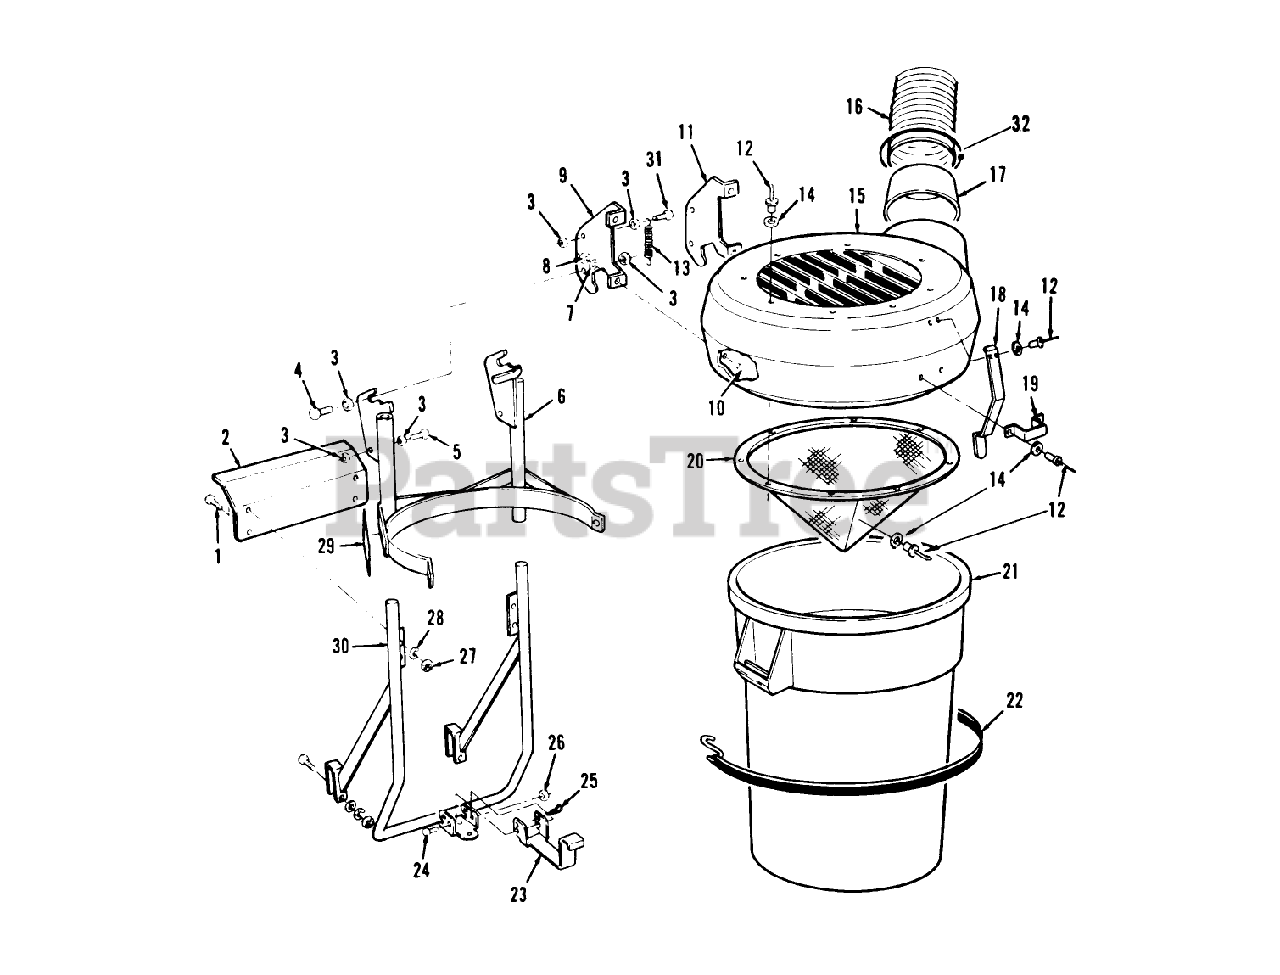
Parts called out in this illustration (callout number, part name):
1	SCREW-HH
2	SHIELD-HEAT B
3	NUT-HEX
4	SCREW-HH
5	SCREW-HH
6	Support-Canister
7	WASHER-PLAIN
8	NUT-LOCK, NI
9	LH TOP BRACKET B
10	SCREW-HH
11	RH TOP BRACKET B
12	RIVET-POP
13	SPRING-EXTENSION
14	Washer
15	TOP-CANISTER
16	HOSE 6" X 48"
17	SEAL ASSEMBLY NP
18	LATCH-BAGGER TOP B
19	BRACKET B
20	SCREEN-BAGGER TOP
21	CANISTER
22	STRAP B
23	BRACKET-SUPT B
24	Screw-Cap Hex. Hd.
25	Hairpin
26	NUT-LOCK, NI
27	NUT-LOCK, NI
28	WASHER-PLAIN
29	DECAL-DANGER
30	MOUNT-BAGGER W.A. B
31	SCREW-HH
